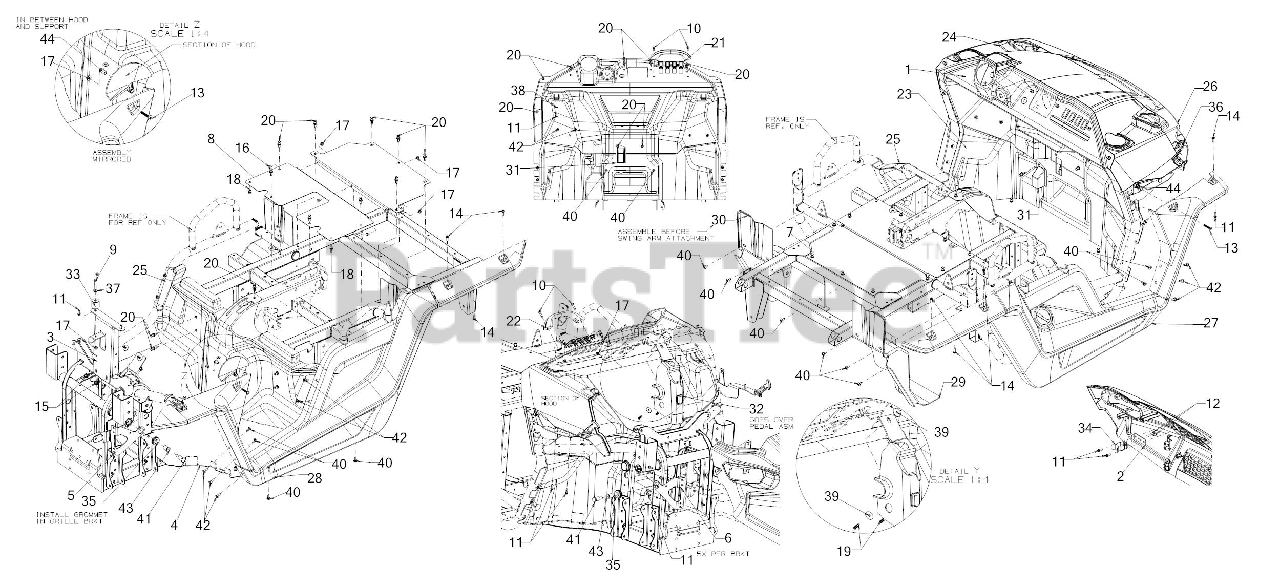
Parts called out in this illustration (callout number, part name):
1	UPPER DASH ASSEMBLY
2	GRILLE MOUNTING BRACKET
3	HOOD FRAME SUPPORT BRACKET
4	FLOOR BOARD PLATE
5	GRILL PIVOT BRACKET (LH)
6	GRILL PIVOT BRACKET (RH)
7	REAR PANEL
8	FRONT PANEL
9	HEX SCREW 1/4-20 x 1.75
10	SCREW 1/4-20 x 1.0
11	SCREW 1/4 x .750
12	SCREW 1/4-20 X.500
13	SCREW 1/4-20 x 1.50
14	SCREW-1/4-15 X 0.750 PHILLIPS
15	SCREW 3/8-16 x .500
16	SCREW 1/4-20X.5 GR5
17	FLANGE LOCK NUT
18	RUBBER PLUG
19	RATCHET CLIP
20	PLASTIC RIVET
21	PANEL SWITCH PLUG
22	GRAB HANDLE
23	UPPER FLOOR BOARD COVER
24	FRONT HOOD
25	FRONT SEAT COVER
26	PIVOT HOOD
27	MIDDLE FENDER (RH)
28	MIDDLE FENDER (LH)
29	INNER FENDER (RH)
30	INNER FENDER (LH)
31	THROTTLE CABLE COVER
32	THROTTLE PEDAL COVER
33	HOOD LATCH ROLLER
34	HOOD LATCH SPRING
35	RUBBER GROMMET
36	HOOD STRAP
37	FLAT WASHER .28 ID x .74 OD x .063
38	FLAT WASHER
39	FLAT WASHER
40	TORX SHOULDER SCREW 1/4-20
41	SHOULDER SCREW .625 x .875 x 3/18
42	SHOULDER SCREW .375X.280:1/4-14
43	FLANGE BEARING
44	SHOULDER SPACER
